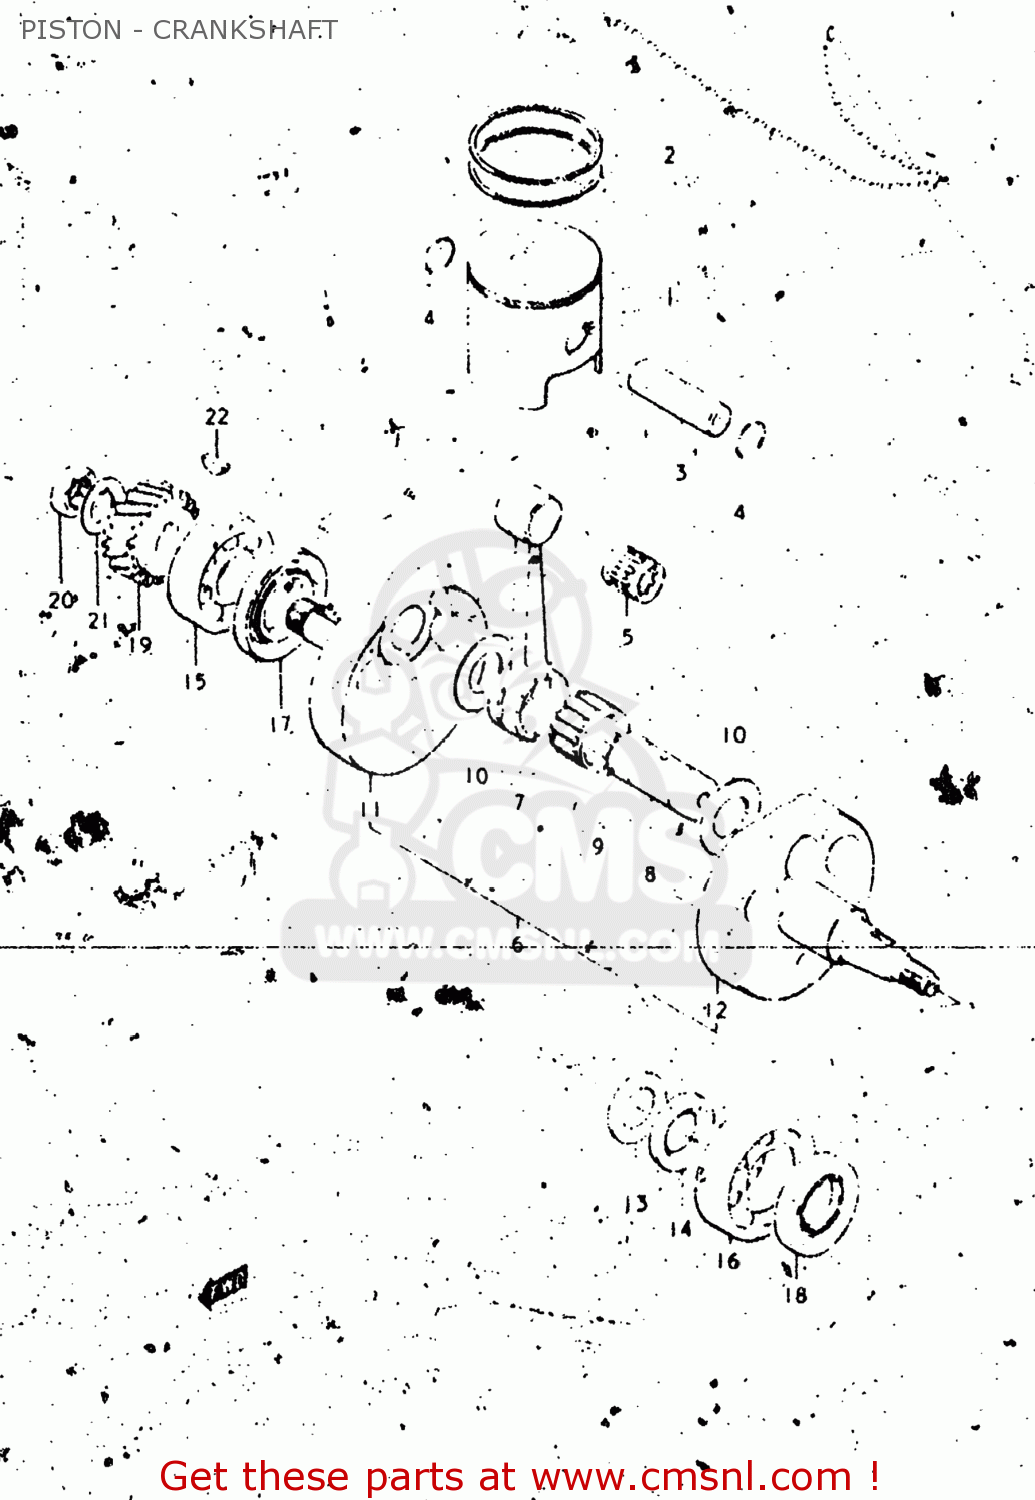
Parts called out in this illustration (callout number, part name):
1	PISTON
2	RING SET,PISTON
3	PIN,PISTON (18MM)
4	CIRCLIP
5	BEARING
6	CRANKSHAFT ASSEMBLY
7	CONNECTING ROD
8	PIN,CRANK
9	BEARING(25X31X20)
10	WASHER
11	CRANKSHAFT
12	CRANKSHAFT,LEFT
13	SHIM
14	SPACER (30X45X4.8)
15	BEARING
16	BEARING
17	SEAL,OIL(35X62X9)
18	OIL SEAL
19	GEAR,PRIMARY DRIVE
20	NUT
21	WASHER
22	KEY
